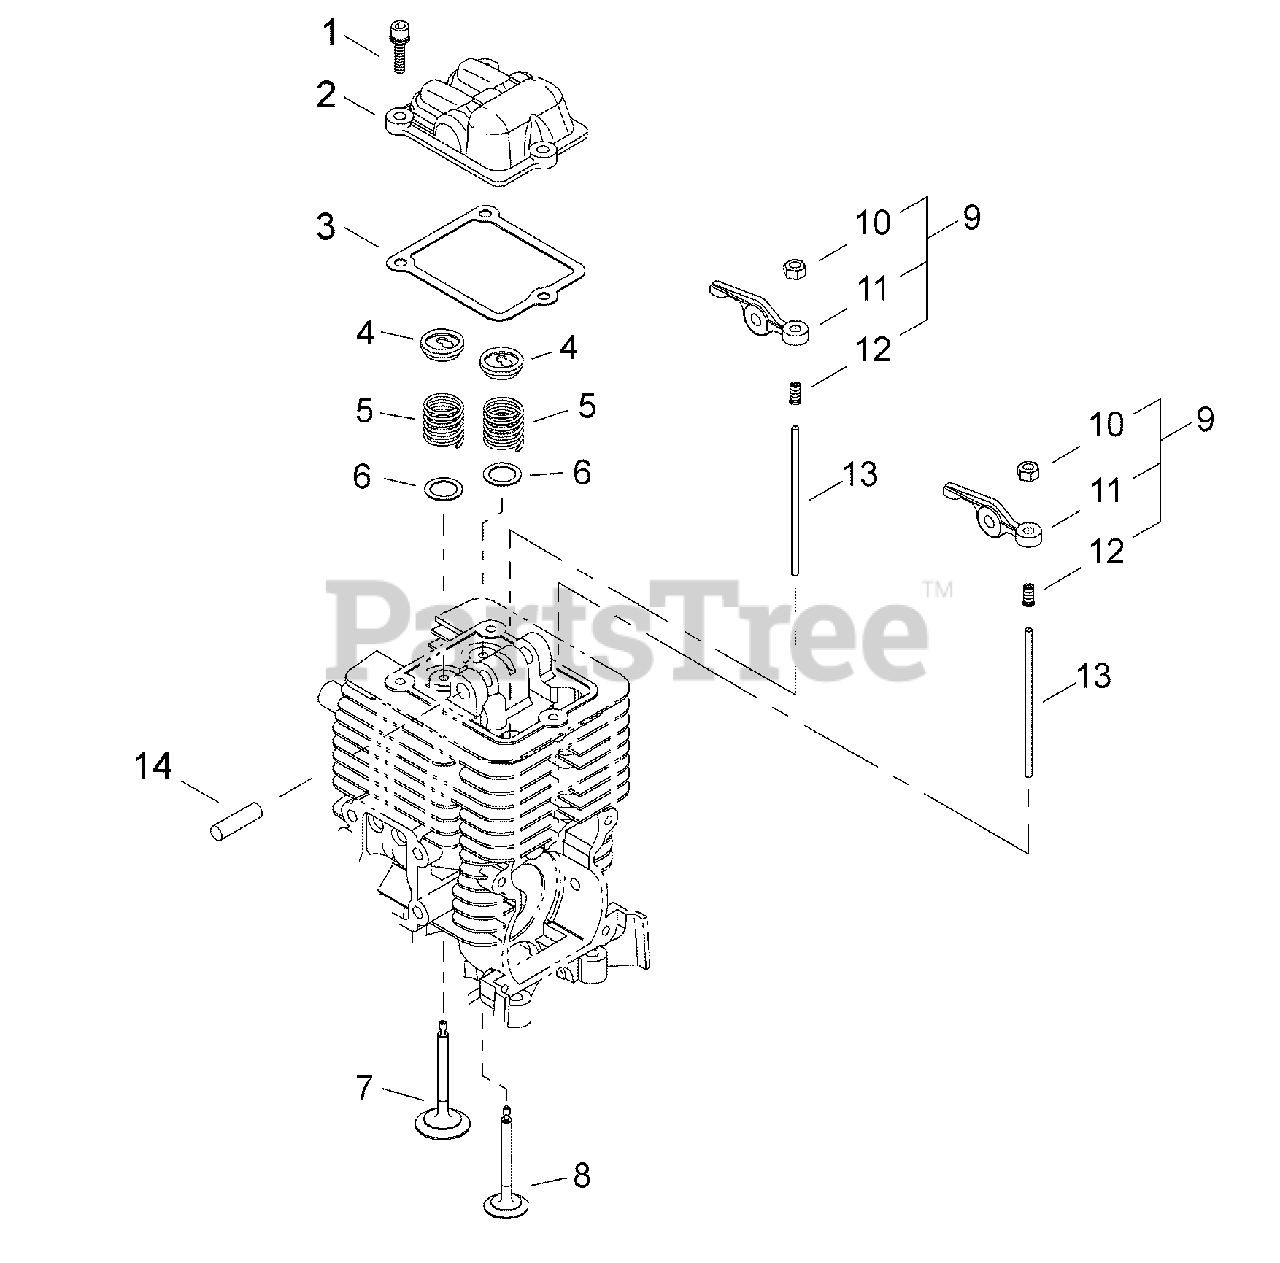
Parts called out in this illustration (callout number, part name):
1	SCREW - 4X14
2	COVER, ROCKER ARM
3	GASKET
4	RETAINER, VALVE
5	SPRING, VALVE
6	WASHER, VALVE - 9
7	VALVE, INTAKE
8	VALVE, EXHAUST
9	ROCKER ARM ASSY
10	LOCKNUT, ADJUSTER
11	ARM, ROCKER
12	SCREW, ADJUST
13	PUSHROD
14	SHAFT, ROCKER ARM - 5X37.8
